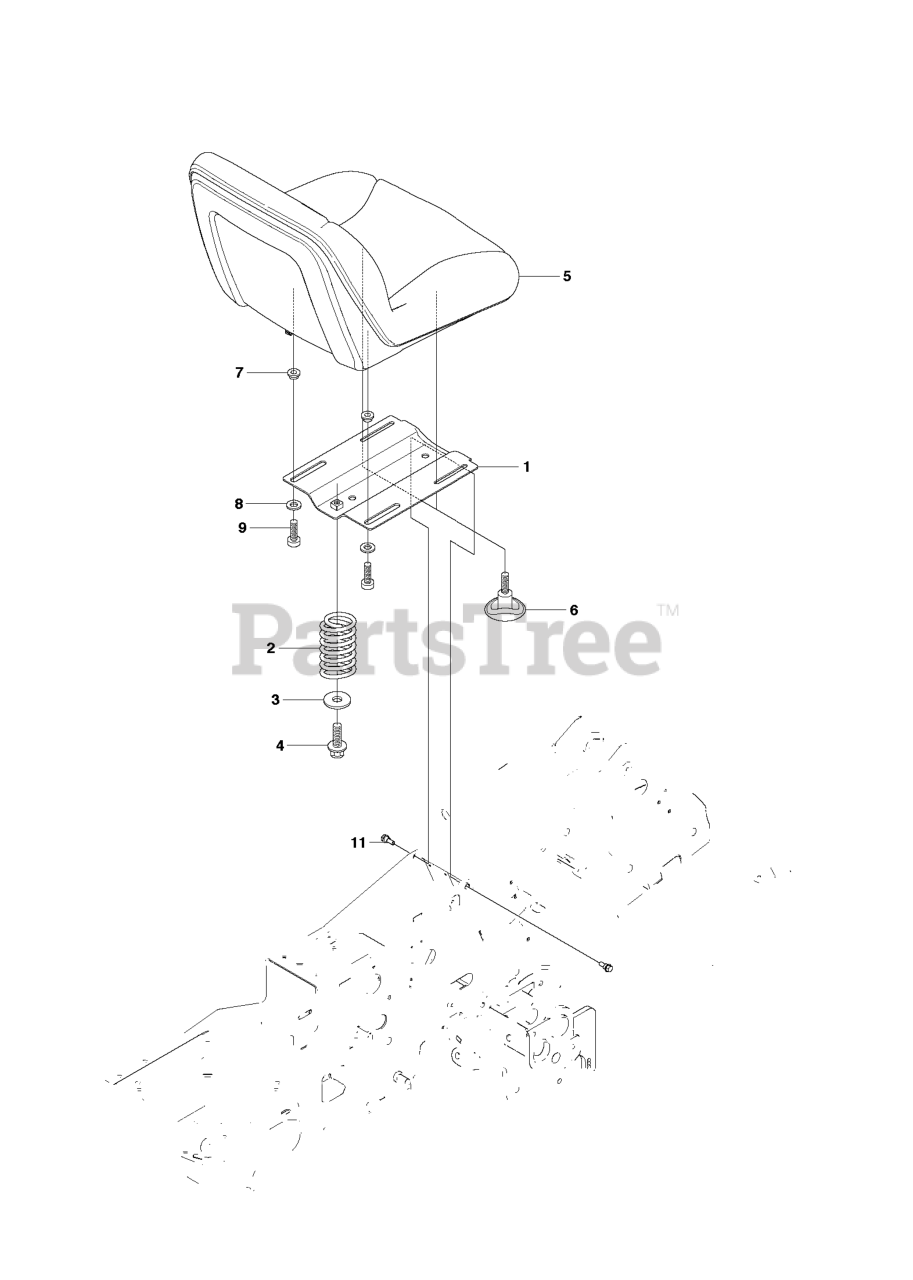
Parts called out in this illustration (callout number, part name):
1	SEAT BRACKET
2	SEAT SPRING
4	Screw M10x25
5	SEAT
6	ADJUSTING KNOB
